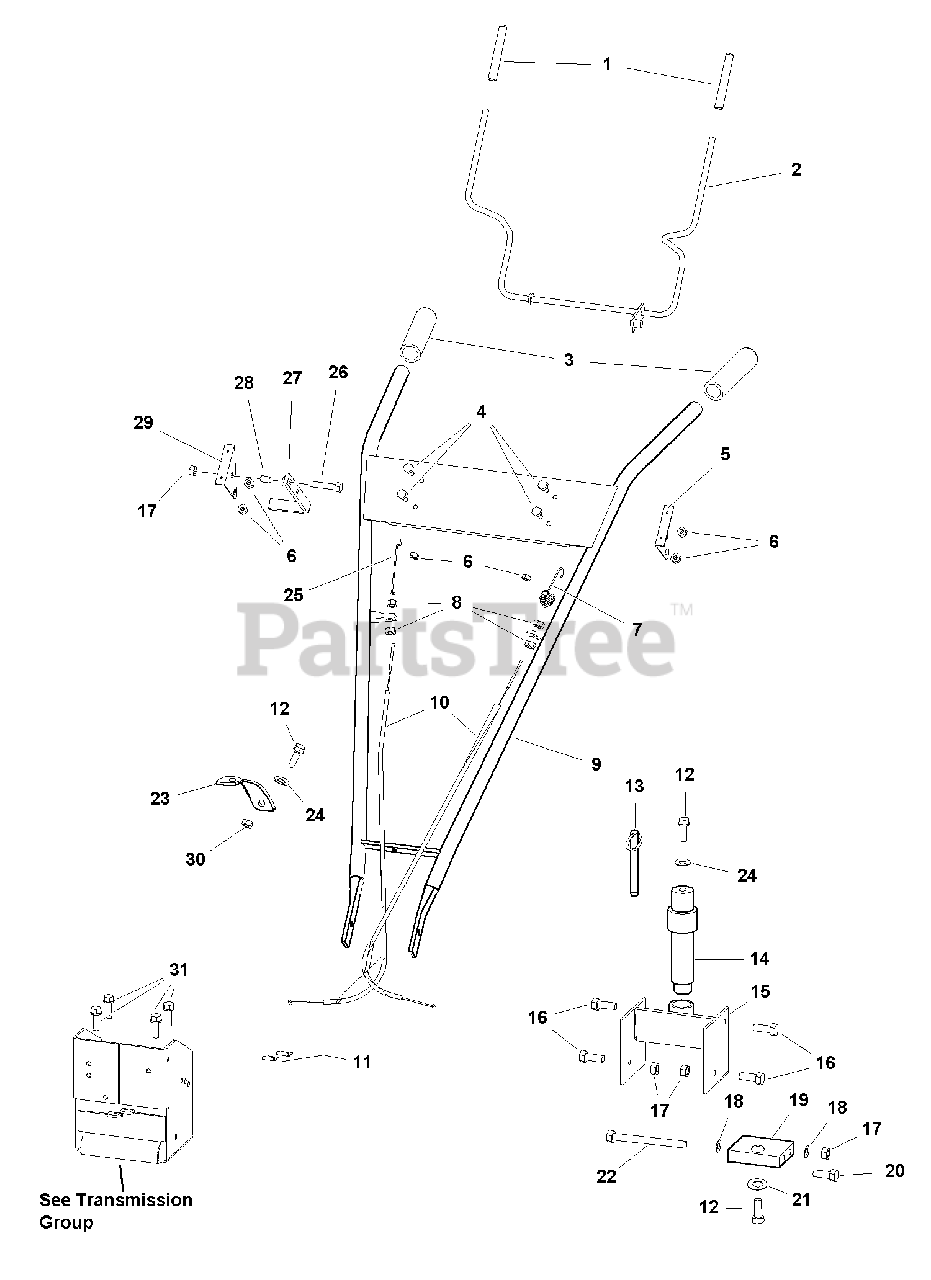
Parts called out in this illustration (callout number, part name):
1	HANDLE GRIP, Drive Control Lever
2	LEVER, Drive Control
3	HANDLE GRIP
4	SCREW, Pan Head Phillips, #10-24 x 1
5	BRACKET, Drive Control Lever LH
6	NUT, Hex Nylock, 10-24
7	SPRING, Forward Cable Adjustment
8	NUT, Hex Jam, 5/16-24
9	HANDLE BAR ASSEMBLY
10	CABLE ASSEMBLY
12	CAPSCREW, Hex Head, 5/16-18 x 3/4
13	PIN, Detent
14	PIVOT ROD ASSEMBLY
15	PIVOT MOUNT ASSEMBLY
16	CAPSCREW, Hex Head, 3/8-16 x 1
17	NUT, Hex, 3/8-16
18	WASHER
19	PIVOT, Handle Bar Mount
20	CAPSCREW, Hex Head, 3/8-16 x 1-1/4
22	CAPSCREW, Hex Head 3/8-16 x 4
23	PIVOT, Hnadle Bar Height Adjustment
25	LINK, Reverse
26	CAPSCREW, Hex Head, 5/16-18 x 1-1/4
27	HANDLE, Reverse
28	BUSHING, Pivot, 5/16
29	BRACKET, Drive Control Lever RH
30	NUT, Hex Flange Tow Way Lock, 5/16-18
31	BOLT, Hex Flange Head, 5/16-18 x 3/4
